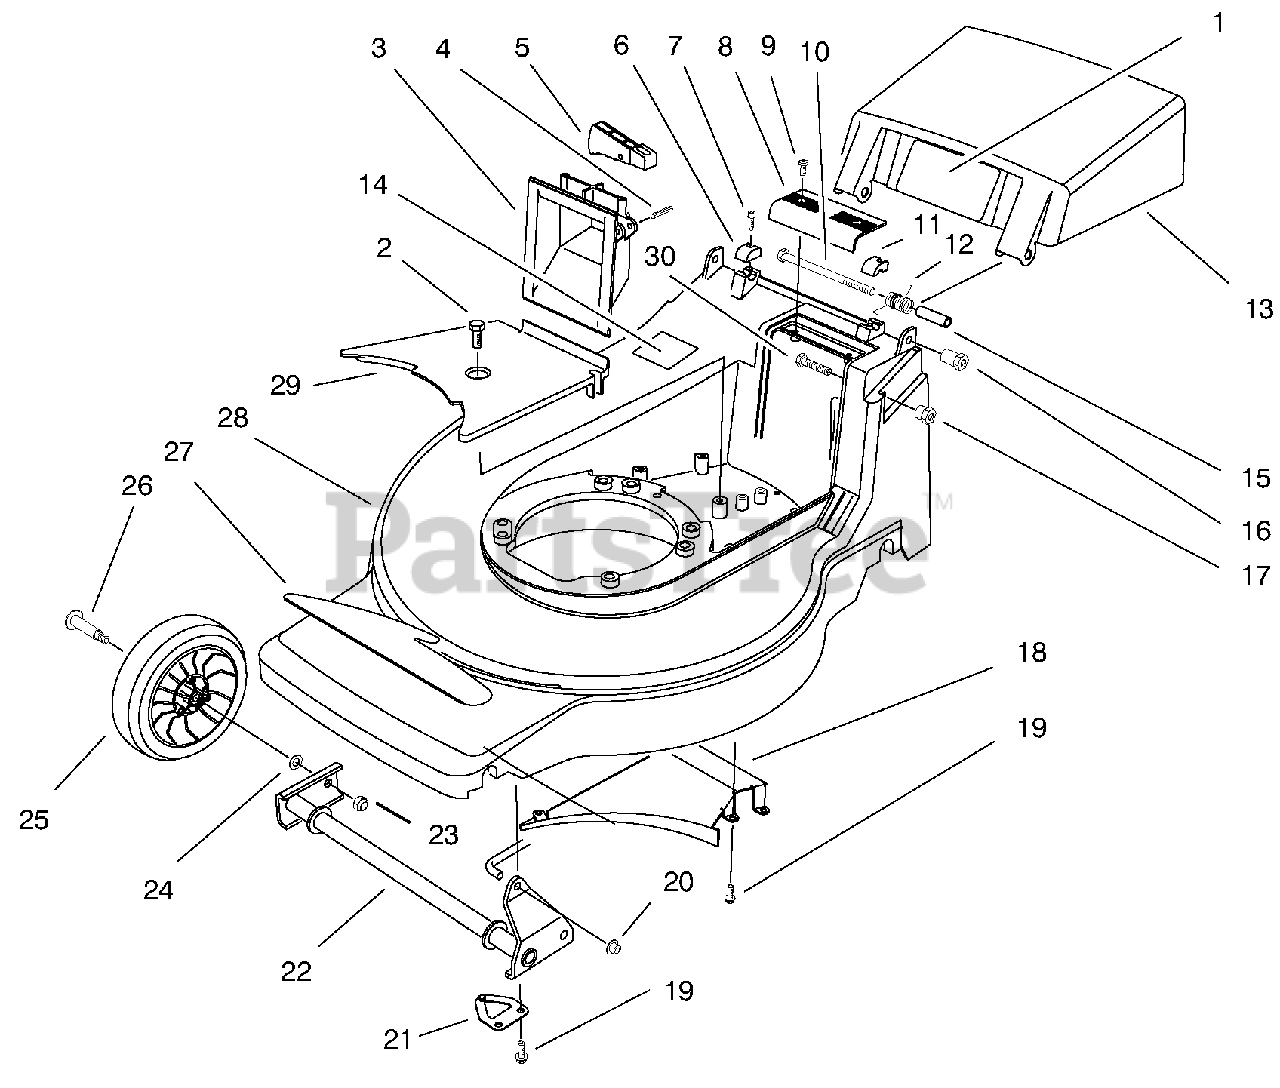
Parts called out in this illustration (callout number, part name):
1	DECAL-DANGER
2	SCREW-HWHTF
3	GRIP - LOWER
4	PIN-SPIRAL
5	TRIGGER - HOC
6	CAP-HINGE BOLT, RH
7	SCREW-HSH
8	GRIP-UPPER
9	SCREW-PPH, PLASTITE
10	5/16-18 X 4 CAPSCREW
11	CAP-HINGE BOLT, LH
12	SPRING-DOOR
13	Door Discharge
14	Decal-Noise
15	DOOR SPACER
16	48CM HANDLE SPACER
17	48CM HANDLE SPACER
18	Ramp-Discharge
19	SCREW-HWH
20	PUSHNUT-CAP, WASHER
21	SHAFT RETAINER ASM
22	PIVOT - FRONT WA
23	Nut-Lock
25	WHL & TIRE ASM 7"
26	WHEEL BOLT
27	DECAL - DECK 450VP
28	Housing (Incl. Ref. #1)
29	BELT COVER
30	5/16-18X1.50 HEX CAPSRW
